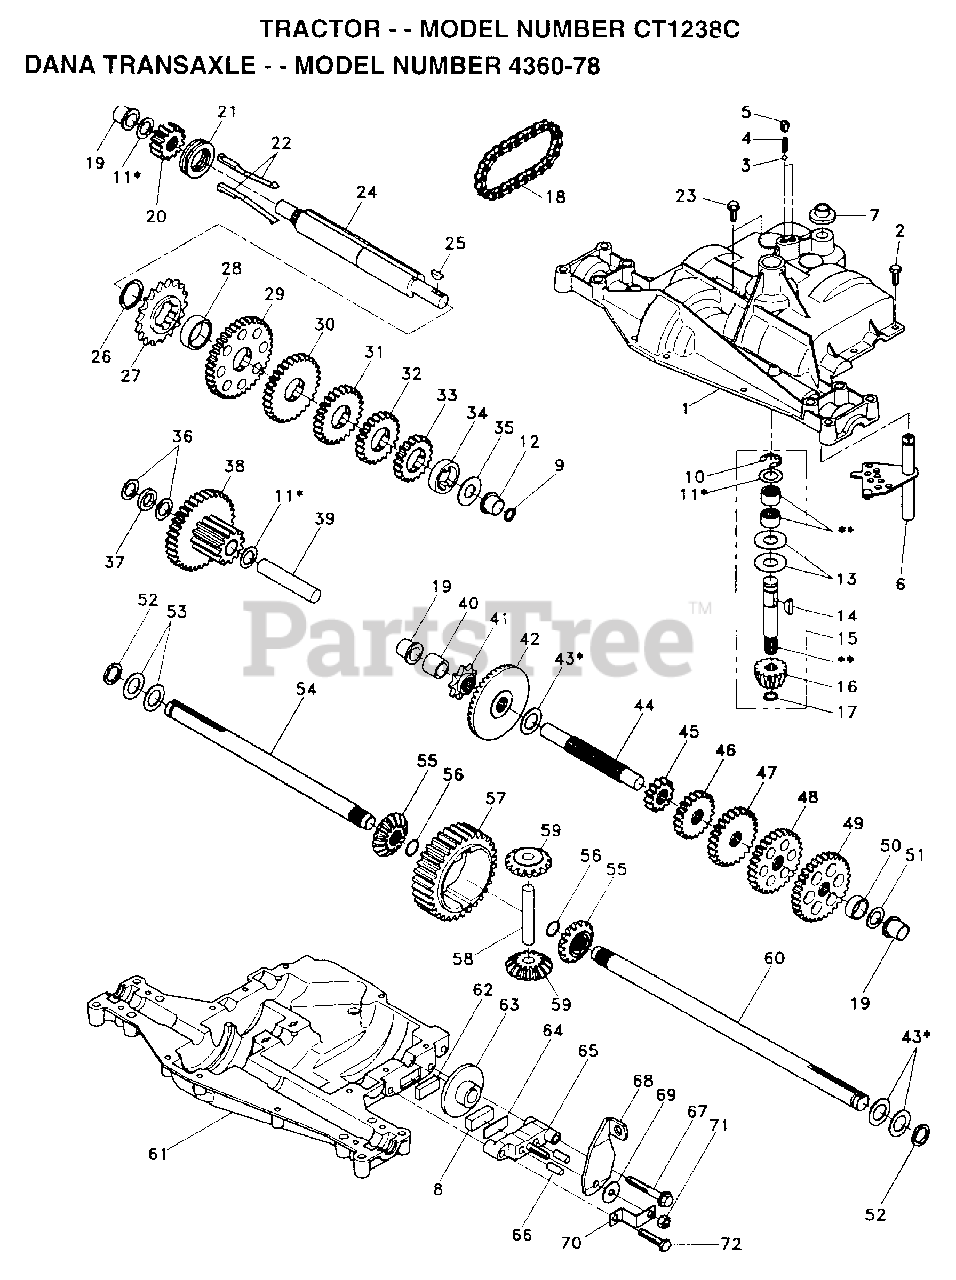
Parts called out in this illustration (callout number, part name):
1	HOUSING UPPER TRN
4	"SPRING, DETENT LT"
5	"SCREW, SET LT"
6	KIT SHIFTER ASM
7	SHIFTER BOOT
8	PUCK T
9	SEAL OIL DANA5416
11	ASM KIT SHIM 4689
13	WASHER T
14	KEY WOODRUFF-DANA
15	AS KIT INPUT SHFT
16	PINION 14T T
17	"RING,RETAINING LT"
18	"CHAIN,24 PTCH LT"
19	BEARING.FLNG.5510
20	GEAR SPUR 14 TTH
21	COLLAR CLUTCH
22	ASM KIT CLTCH KEY
23	SCREW TAP W/SEAL
24	SHAFT INTERM DANA
25	WOODRUFF KEY
26	"RING,RETAINING LT"
27	SPROCKET 18T T
28	SPACER YT
29	GEAR SPUR 37 TTH
31	GEAR 25T LT
32	GEAR SPUR 22 TT
33	SPUR GEAR 19T
34	SPACER
35	"WASHER, PLAIN LT"
36	WASHER 025
37	SPACER
38	ASSM GEAR COMB
39	SHAFT IDLER
40	SPACER T
41	SPROCKET 9T LT
43	ASM KIT SHIM
44	SHAFT T
45	GEAR SPUR 12 TTH
47	"GEAR, SPUR 25T LT"
48	GEAR 28T T
49	"GEAR, SPUR 31T LT"
51	WASHER 060
52	NEOPRENE WASHER
53	WASHER 031
55	GEAR 15T T
56	"RING,RETAINING LT"
58	SHAFT T
59	GEAR 1ST T
61	HOUSING LOWER TNS
62	PUCK T
63	BRAKE DISC. T
64	SPACER LT
66	PIN T
69	WASHER LT
71	NUT.LOCK.5/16-24
72	"SCREW, TAPPING LT"
